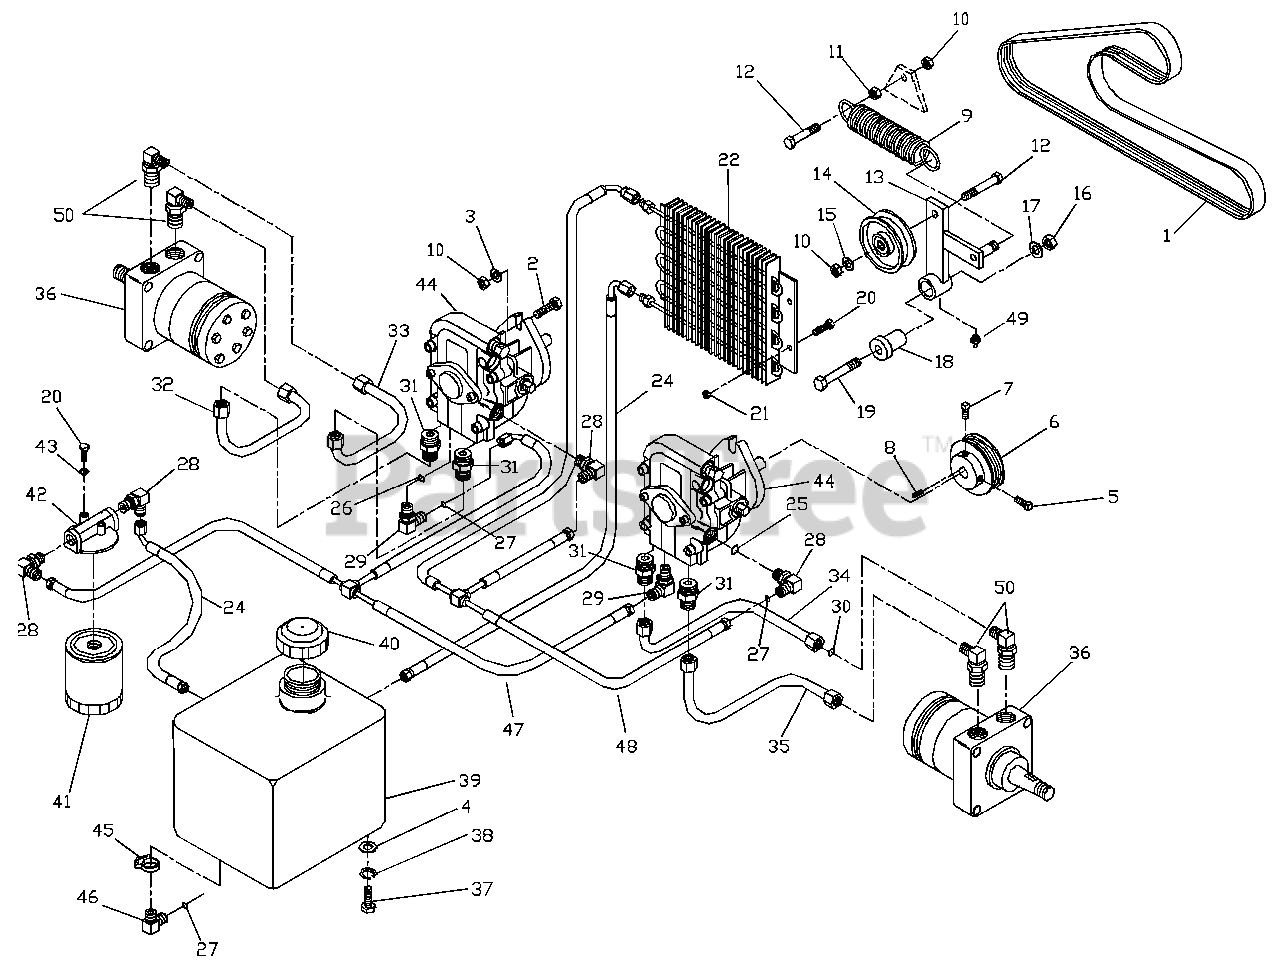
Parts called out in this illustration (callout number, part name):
1	PUMP DRIVE BELT
2	3/8C X 1 1/4 HEX CAP SCREW
3	3/8 FLAT WASHER
4	5/16 FLAT WASHER
5	5/16C X 1 SQ HEAD SET SCREW
6	PUMP PULLEY
7	5/16C X 3/4 SQ HEAD SET SCREW
8	KEY, 5MM SQ X 25MM
10	3/8C CENTERLOCK NUT
11	3/8C WHIZ NUT
12	3/8C X 1 3/4 HEX CAP SCREW
14	IDLER PULLEY
15	3/8 SAE FLAT WASHER
16	1/2C NYLOC NUT
17	1/2 FLAT WASHER
18	IDLER BUSHING
19	1/2C X 3 HEX CAP SCREW
20	1/4C X 5/8 HEX CAP SCREW
21	1/4C CENTERLOCK NUT
24	3/8 HYDRAULIC HOSE 15 1/2" 90
31	STRAIGHT FITTING
36	WHEEL MOTOR
37	5/16C X 3/4 HEX CAP SCREW
38	5/16 LOCK WASHER
39	HYDRAULIC TANK W/FITTINGS
40	HYDRAULIC TANK CAP
41	HYDRAULIC OIL FILTER
42	FILTER HEAD
43	1/4 LOCK WASHER
44	HYDRAULIC PUMP
46	90 DEG. FITTING
47	TEE HOSE ASSY
48	TEE HOSE ASSY
49	1/4-28 ZERK
50	FITTING, 90 DEGREE
